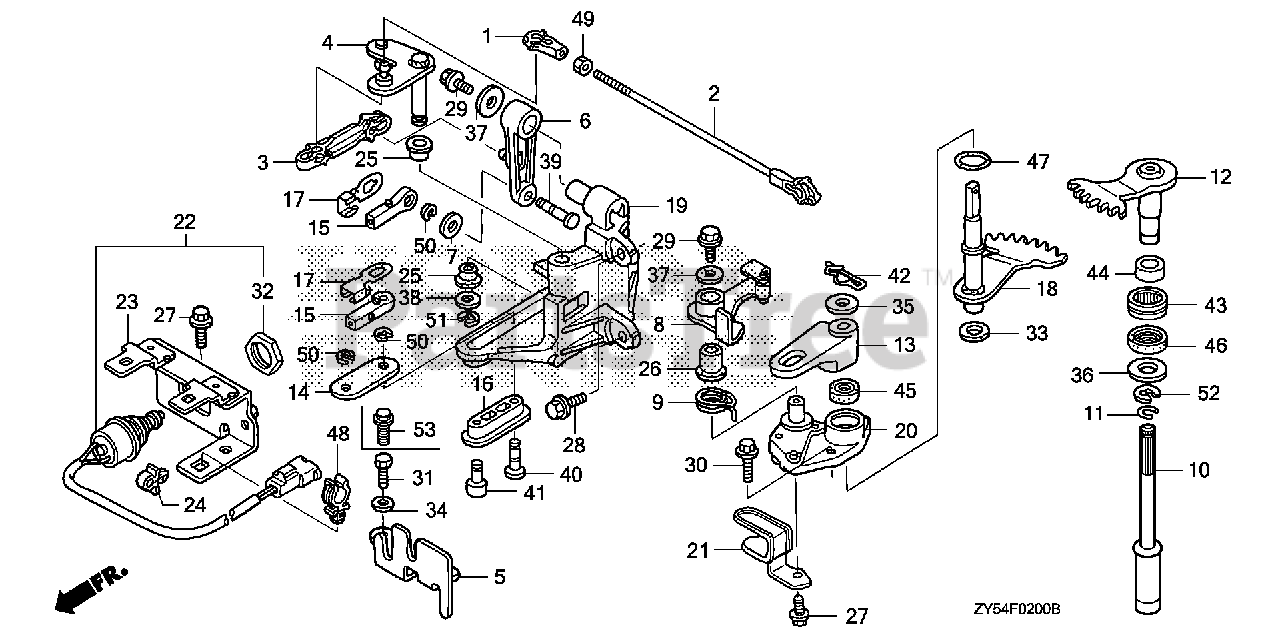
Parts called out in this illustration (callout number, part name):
1	LINKAGE, PIVOT
2	ROD, THROTTLE
3	LINK, THROTTLE
4	PLATE, THROTTLE
5	PLATE, REMOTE CONTROL CABLE
6	ARM, THROTTLE
7	WASHER, PIVOT
8	ARM, CLICK
9	SPRING, CLICK
10	ROD A, SHIFT (XL)
11	RING, STOPPER
12	SHAFT A, SHIFT
13	ARM, SHIFT
14	PLATE, SHIFT PIVOT
15	PIVOT, SHIFT
16	PIVOT, SHIFT SLIDE
17	PLATE, LOCK
18	SHAFT B, SHIFT
19	BRACKET, SHIFT LINK
20	HOLDER, SEAL *NH8* (DARK GRAY)
21	BRACKET A, CABLE
22	SWITCH ASSY., NEUTRAL
23	BRACKET, NEUTRAL SWITCH
24	CLIP, BRAKE PIPE (A) (FOR NEUTRAL SWITCH)
25	BUSH A, COVER LOCK
26	BUSH, BLADE BRAKE
27	BOLT, FLANGE (6X14)
28	BOLT, FLANGE (6X18)
29	BOLT, FLANGE (6X12) Use from Frame SN 1005249.
30	BOLT, FLANGE (6X20) (ENGINE NO.)
31	BOLT, HEX. (6X16)
32	NUT, HEX. (20MM) Use up to Frame SN 1300359.
33	WASHER, SHIFT SHAFT
34	WASHER, PLAIN (6MM) Use up to Frame SN 4800342.
35	WASHER, PLAIN (12MM)
37	WASHER, PLAIN (6MM)
38	WASHER, PLAIN (8MM) Use from Frame SN 4800713.
40	PIN, SHIFT LINK
42	PIN, SNAP (12MM)
43	BEARING, NEEDLE (20X28X13) (SOLID)
44	RING (INNER) (15X20X13)
45	OIL SEAL (14X26X6)
46	SEAL, WATER (14X26X8)
47	O-RING (25X2.4) (NOK)
48	HOLDER, DRAIN TUBE
49	NUT, HEX. (5MM)
50	E-RING (4MM)
51	E-RING (6MM)
52	E-RING (12MM)
53	BOLT, FLANGE (6X16)
